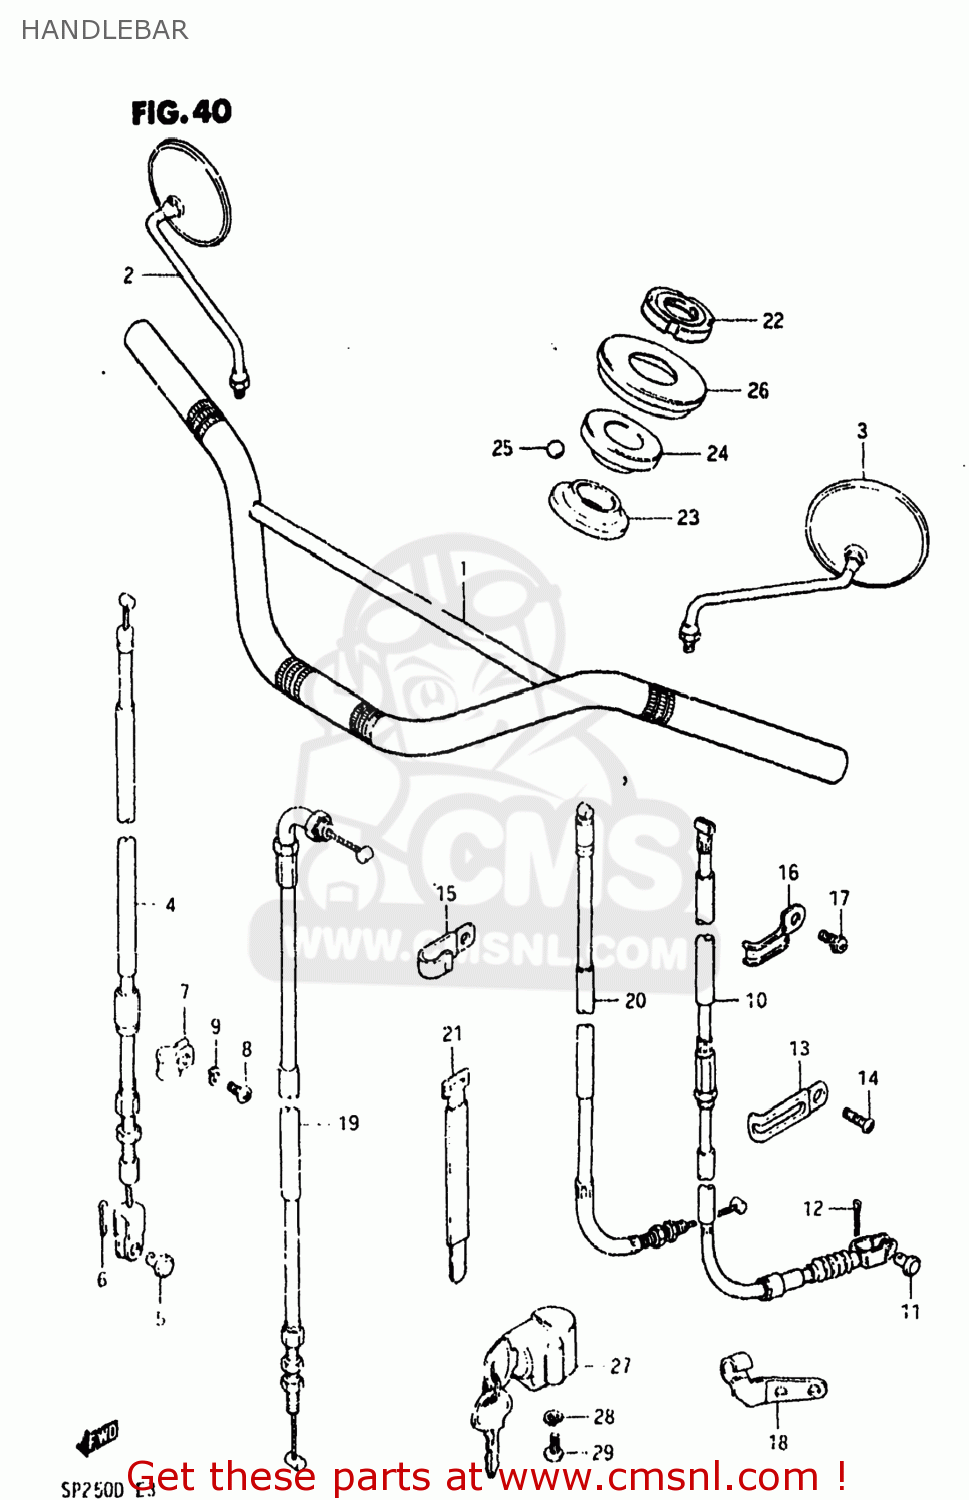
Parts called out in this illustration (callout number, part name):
1	HANDLEBAR
2	MIRROR ASSEMBLY,RIGHT
3	MIRROR ASSEMBLY,LEFT
4	CABLE ASSY,FR BRAKE
5	PIN(L:17.5)
6	PIN
7	CLAMP,FR BRAKE CABLE
8	SCREW
9	LOCK WASHER
10	CABLE ASSEMBLY,CLUTCH
11	PIN(L:13)
12	PIN
13	CLAMP
14	SCREW 6X12
15	CLAMP
16	CLAMP
17	SCREW
18	STOPPER,CLUTCH CABLE
19	CABLE ASSY,THROTTLE NO.1
20	CABLE ASSEMBLY,DECOMPRESSION
21	CLAMP(L:250)
22	NUT,STEERING STEM
23	RACE,STEERING,INNER,UPPER
24	RACE,STEERING,OUTER,UPPER
25	BALL
26	SEAL,STEERING UPR DUST
27	LOCK ASSY,STEERING
28	LOCK WASHER
29	SCREW
